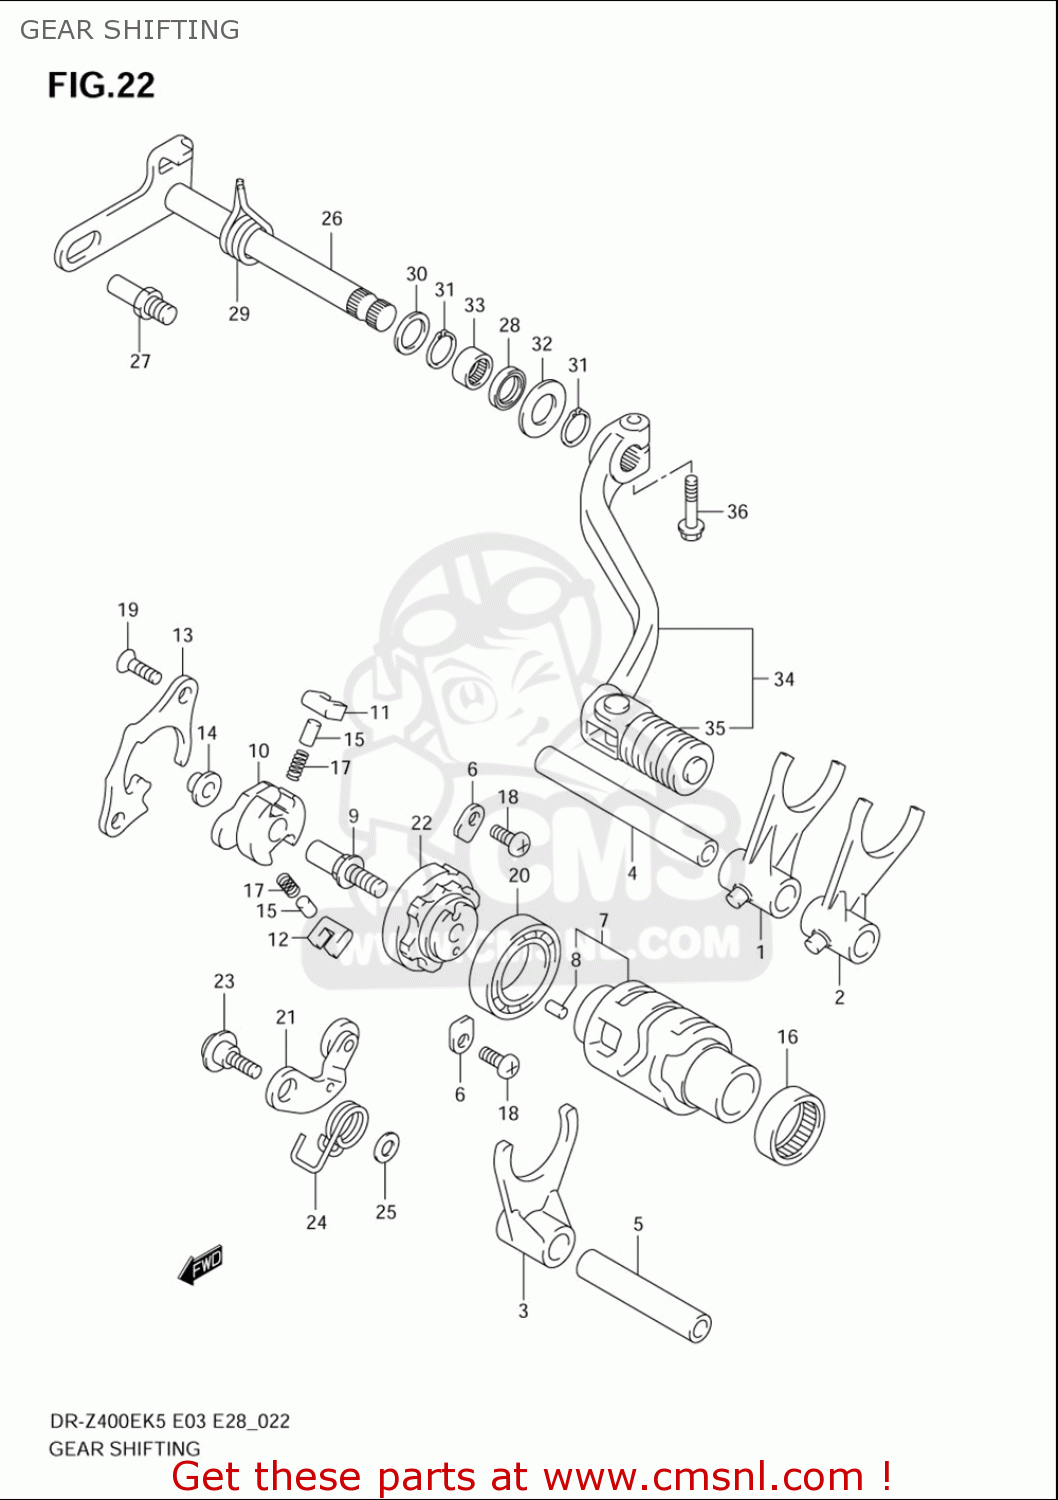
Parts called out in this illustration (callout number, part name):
1	FORK,GEAR SHIFT NO.1
2	FORK,GEAR SHIFT NO.2
3	FORK,GEAR SHIFT NO.3
4	SHAFT,GEAR SHIFT FORK(L:95)
5	SHAFT,GEAR SHIFT FORK(L:60)
6	RETAINER
7	CAM,GEAR SHIFT
8	PIN
9	PIN,SHIFT CAM DRIVEN GEAR
10	SHIFTER,GEAR SHIFT CAM
11	PAWL,GEAR SHIFT NO.1
12	PAWL,GEAR SHIFT NO.2
13	LIFTER,GEAR SHIFT PAWL
14	SPACER(7X10X5)
15	PIN(5X8)
16	BEARING(25X32X12)
17	SPRING
18	BOLT(6X12)
19	SCREW(6X12)
20	BEARING
21	STOPPER,GEAR SHIFT CAM
22	PLATE,GEAR SHIFT STOPPER
23	BOLT,CAM STOPPER ARM
24	SPRING,SHIFT CAM STOPPER
25	WASHER
26	SHAFT,GEAR SHIFT
27	STOPPER,SHIFT ARM
28	SEAL,OIL(14X22X6)
29	SPRING
30	SHIM(14X20X1)
31	CIRCLIP
32	WASHER
33	BEARING(14X20X12)
34	LEVER ASSY,GEAR SHIFT
35	RUBBER,GEAR SHIFT PEDAL
36	SCREW
